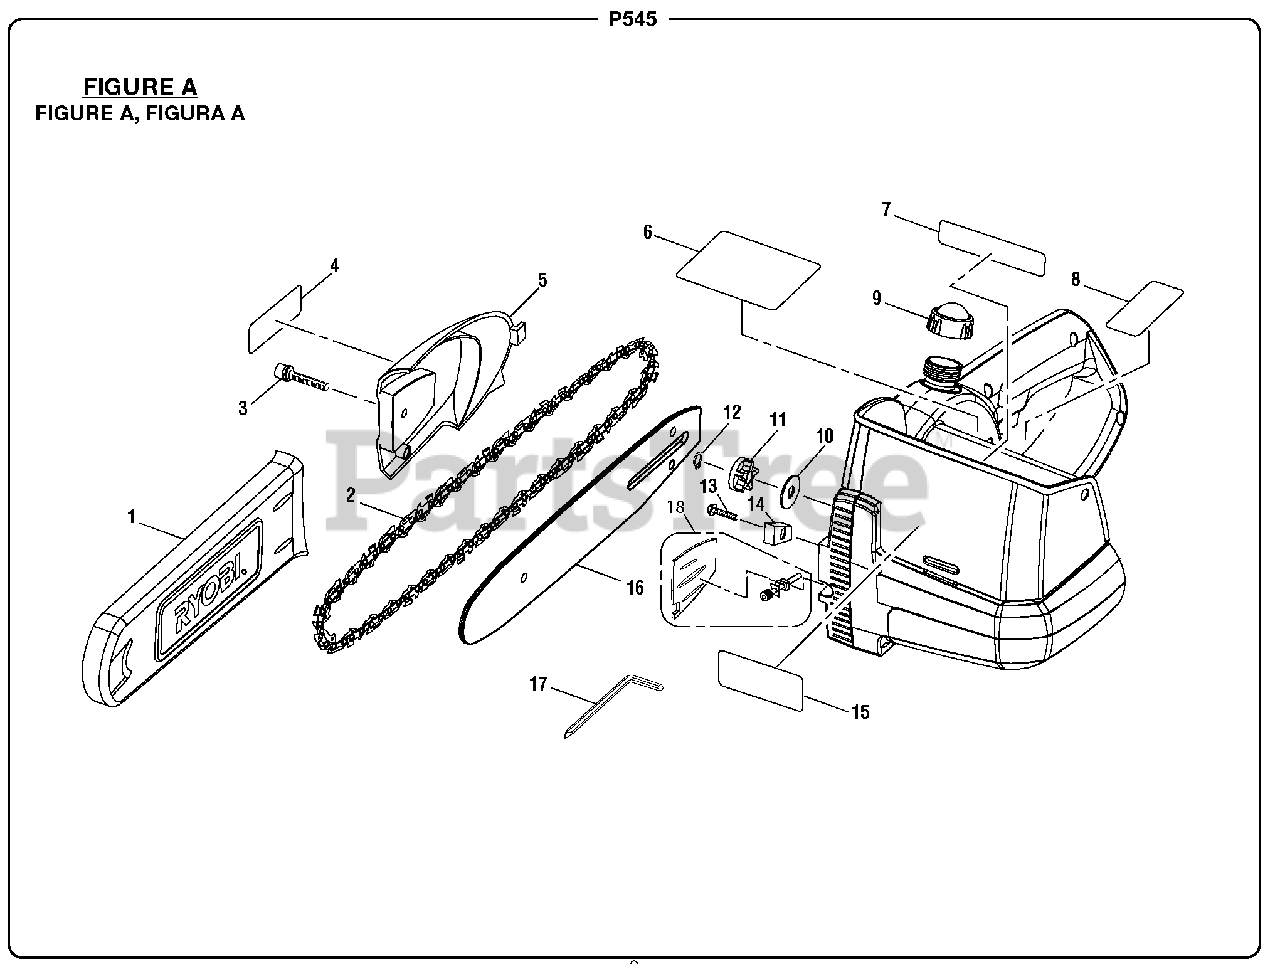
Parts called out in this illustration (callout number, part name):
2	Chain (Oregon, 90JG-040)
3	Screw w/Washer (M6 x 35 mm, Soc. Hd.)
4	Logo Label (Side)
5	Bar Cover
6	Warning Label (On Handle)
7	Icon Label
8	Data Label
9	Oil Cap Assembly
12	Retaining Ring
13	Screw (M2.3 x 6 mm)
15	Logo Label (Front)
16	Saw Bar (10 in.) (Carlton)
17	Hex Key (5 mm)
18	Chain Tension Assembly
